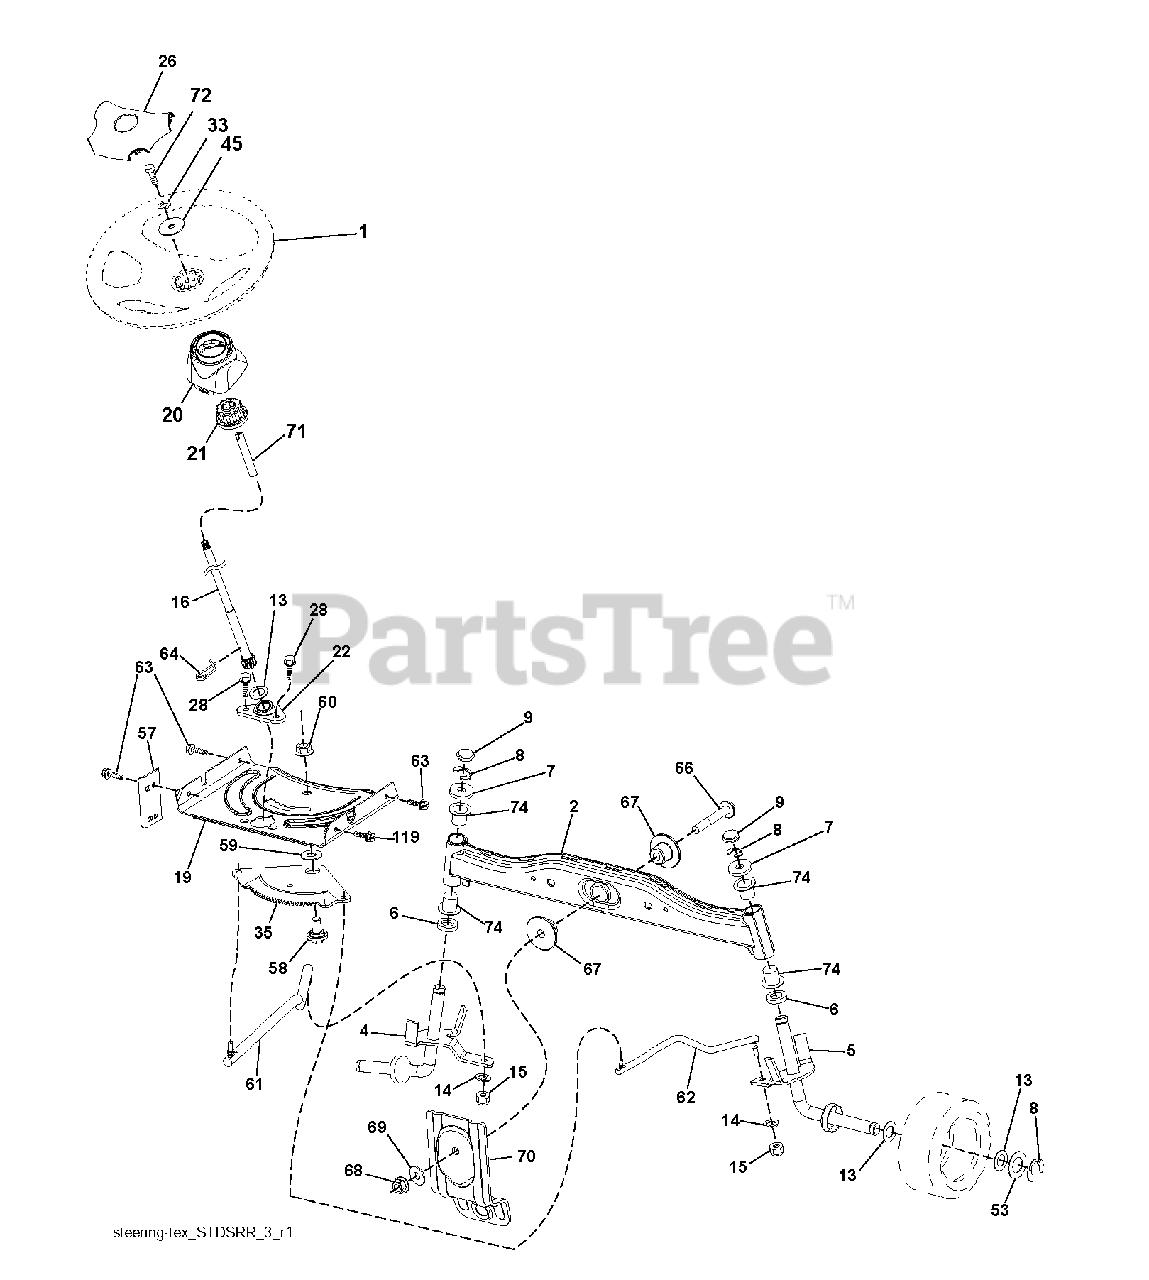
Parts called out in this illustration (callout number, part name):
1	WHEEL.STEERING.STDSRR.BLK/OV
2	AXLE HALF ASM-WELDED
8	RING CLIP
9	CAP.SPINDLE
14	WASHER, LOCK 3/8
15	NUT CROWNLOCK 3/8-24
16	SHAFT STEERING
19	PLATE.STEER.DDL.NLT/NG
20	BOOT.STEERING.PREDATOR.LT.BLAC
21	ADAPTER, WHEEL STNG..
22	BUSHING.ASM.STEERING.A
26	CAP.WHL.STRNG.STDSRRD.SRS.BLK
28	SCREW, 3/8-16X3/4
33	LOCKWASHER
35	GEAR.SECTOR.PLATE.DDL.
45	WASHER.11/32
53	WASHER.HARDENED
57	BRACKET.UPSTOP.TEX
58	BOLT.SHOULDER.SECTOR.P
59	WASHER.THURST.SECTOR.S
60	NUT FLANGE LOCK 5/8-11
61	DRAGLINK.LH.BALLSTUD.D
62	DRAGLINK.RH.BALLSTUD.D
63	SCREW
64	RETAINER.CLIP.SPRING.S
66	BOLT HEX FGHD 7/16-14 X 3 SERR
67	BUSHING.PM.FRONT AXLE
68	NUT.LOCK.FLANGE.7/16
69	WASHER.1.5X.505X.118
71	SHAFT EXTENSION STEERING
72	BOLT YT
74	BRNG T
119	SHOULDER BOLT 5/16-18TT
